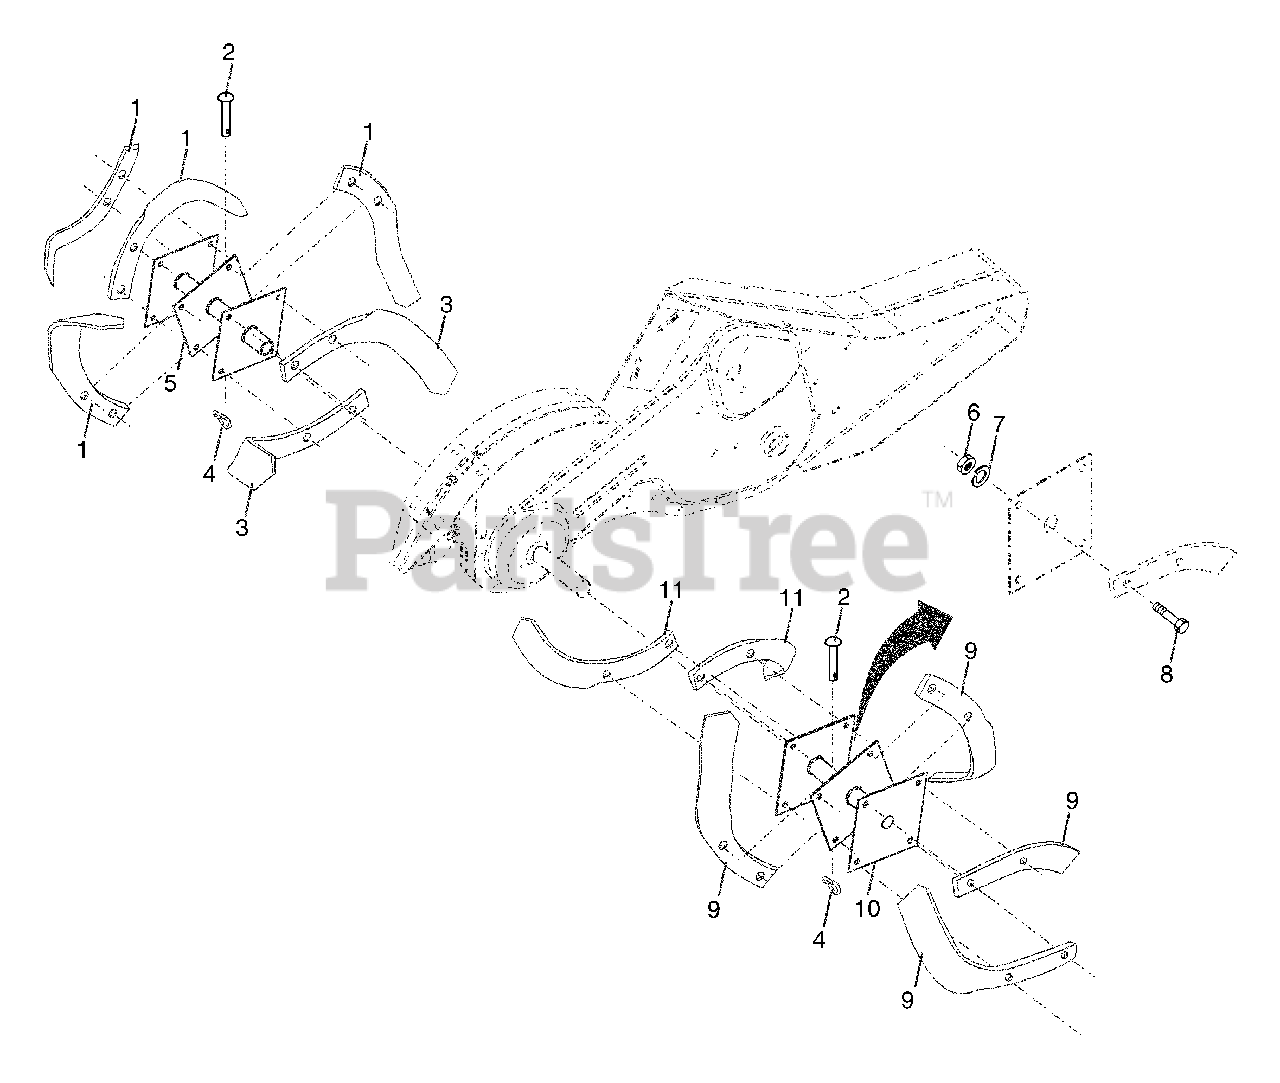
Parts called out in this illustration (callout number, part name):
1	Tine, Outer, L.H.
2	Clevis Pin
3	Tine, Inner, L.H.
4	Clip, Hairpin
5	Assembly, Hub and Plate, L.H.
6	Nut, Hex 3/8-24
7	Washer, Lock 3/8
8	Bolt, Hex 3/8-24 x 1
9	Tine, Outer, R.H.
10	Assembly, Hub and Plate, R.H.
11	Tine, Inner, R.H.
